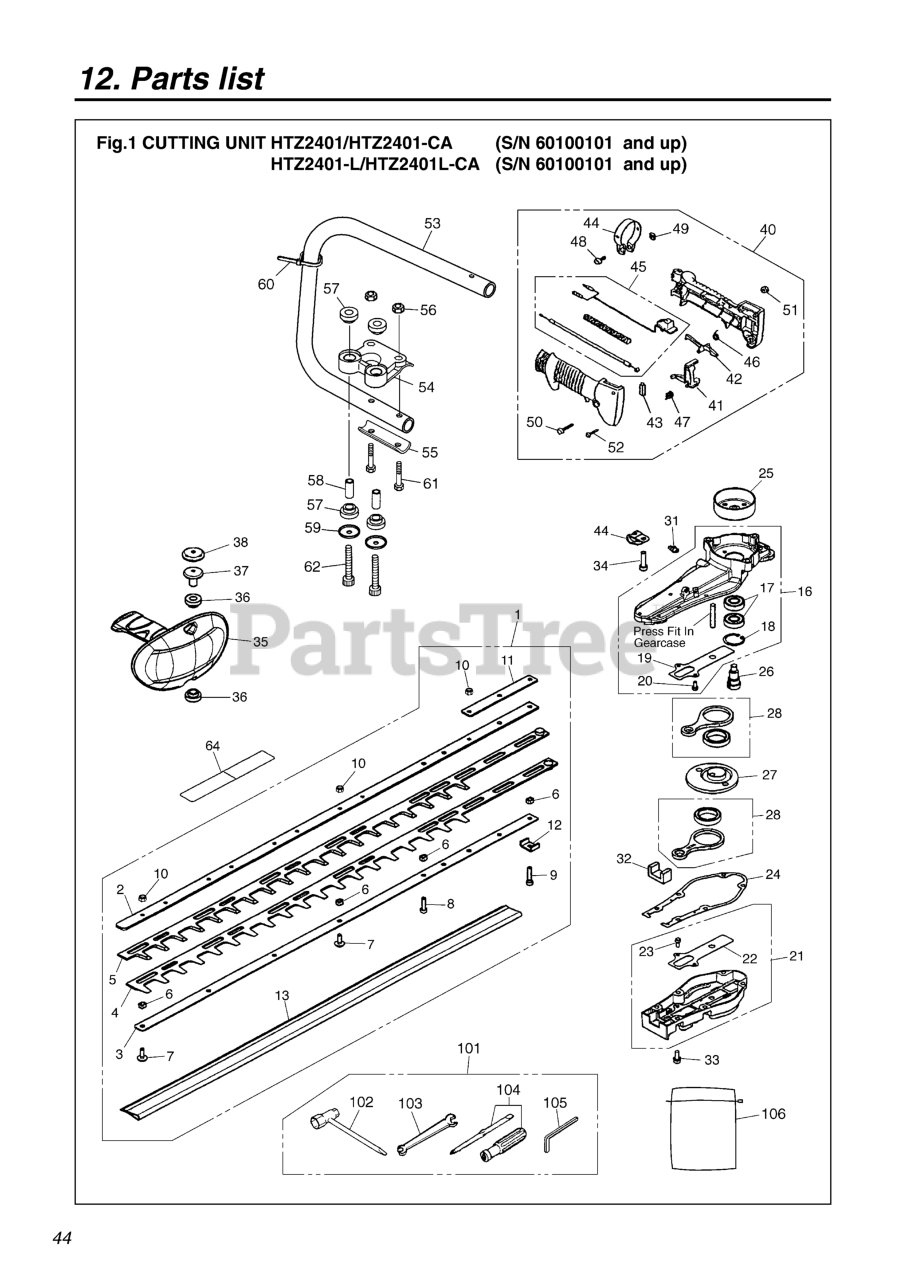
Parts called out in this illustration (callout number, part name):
1	BLADE ASSY
2	PLATE.UPPER
3	PLATE, LOWER
4	BLADE,LOWER
5	BLADE,UPPER
6	SPACER
7	SCREW, BLADE
8	BOLT, M5 X 20
9	BOLT
10	NUT
11	PLATE
12	BRACKET (RPLS T4543-11510)
13	COVER, BLADE
16	GEARCASE-C (RPLS. -6111)
17	BEARING
18	RING, SNAP, M28 x 1.2
20	BOLT
21	CASE-BOTTOM-A
23	BOLT
24	GASKET
26	GEAR, DRIVE
27	GEAR, DRIVEN
28	ROD-A
31	FITTING, GREASE
32	FELT
33	BOLT
34	BOLT, M6 X 25
35	SPACER
36	SPACER
37	HOLDER
38	CAP
40	LEVER-ASSY
41	LEVER
42	LEVER
43	TOP
44	BAND
45	CABLE-ASSY
46	SPRING
47	SPRING
49	NUT
50	SCREW
51	NUT
52	SCREW
53	PIPE
54	MOUNT
56	NUT
57	ABSORBER
58	COLLAR
59	WASHER
61	BOLT, M5 X 30
62	BOLT
64	LABEL
101	TOOL-SET
103	SPANNER, 8 X 10 (RPLS 2540- )
104	SCREWDRIVER
105	WRENCH (TOOL)
